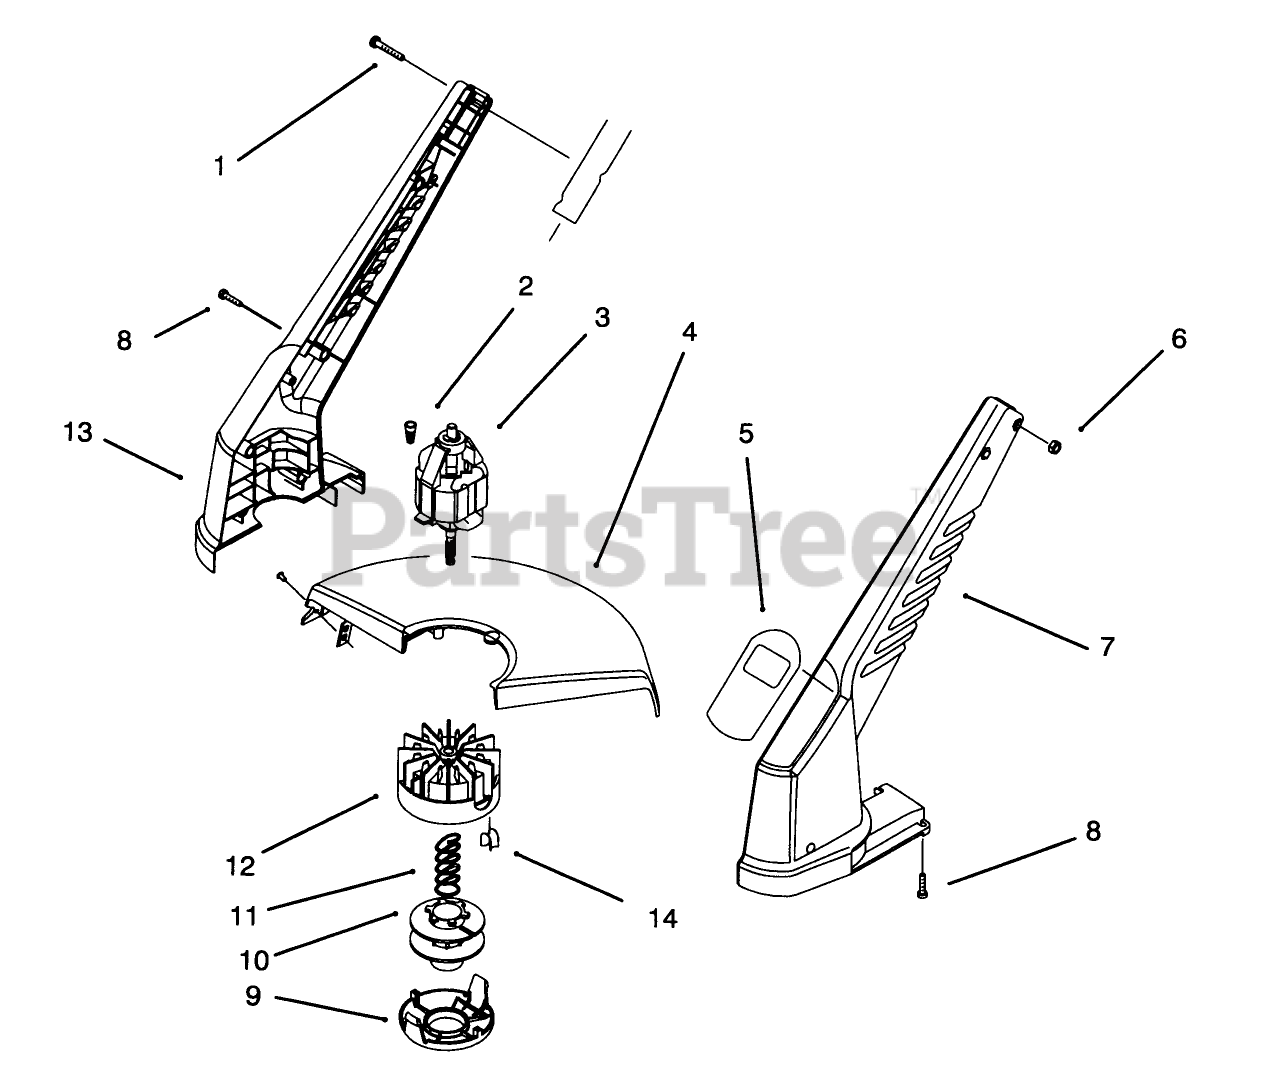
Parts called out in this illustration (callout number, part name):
1	SCREW-PPH
2	CONNECTOR-NUT, WIRE
3	Motor Assembly (Incl. Ref.#12 & 14)
4	SHIELD ASM - SERVICE
5	DECAL - 14" TRIMMER
6	NUT-HEX
7	LH HOUSING
8	Screw
10	SPOOL-LARGE
11	SPRING-COMPRESSION
12	Drum
13	RH HOUSING
14	EYELET
